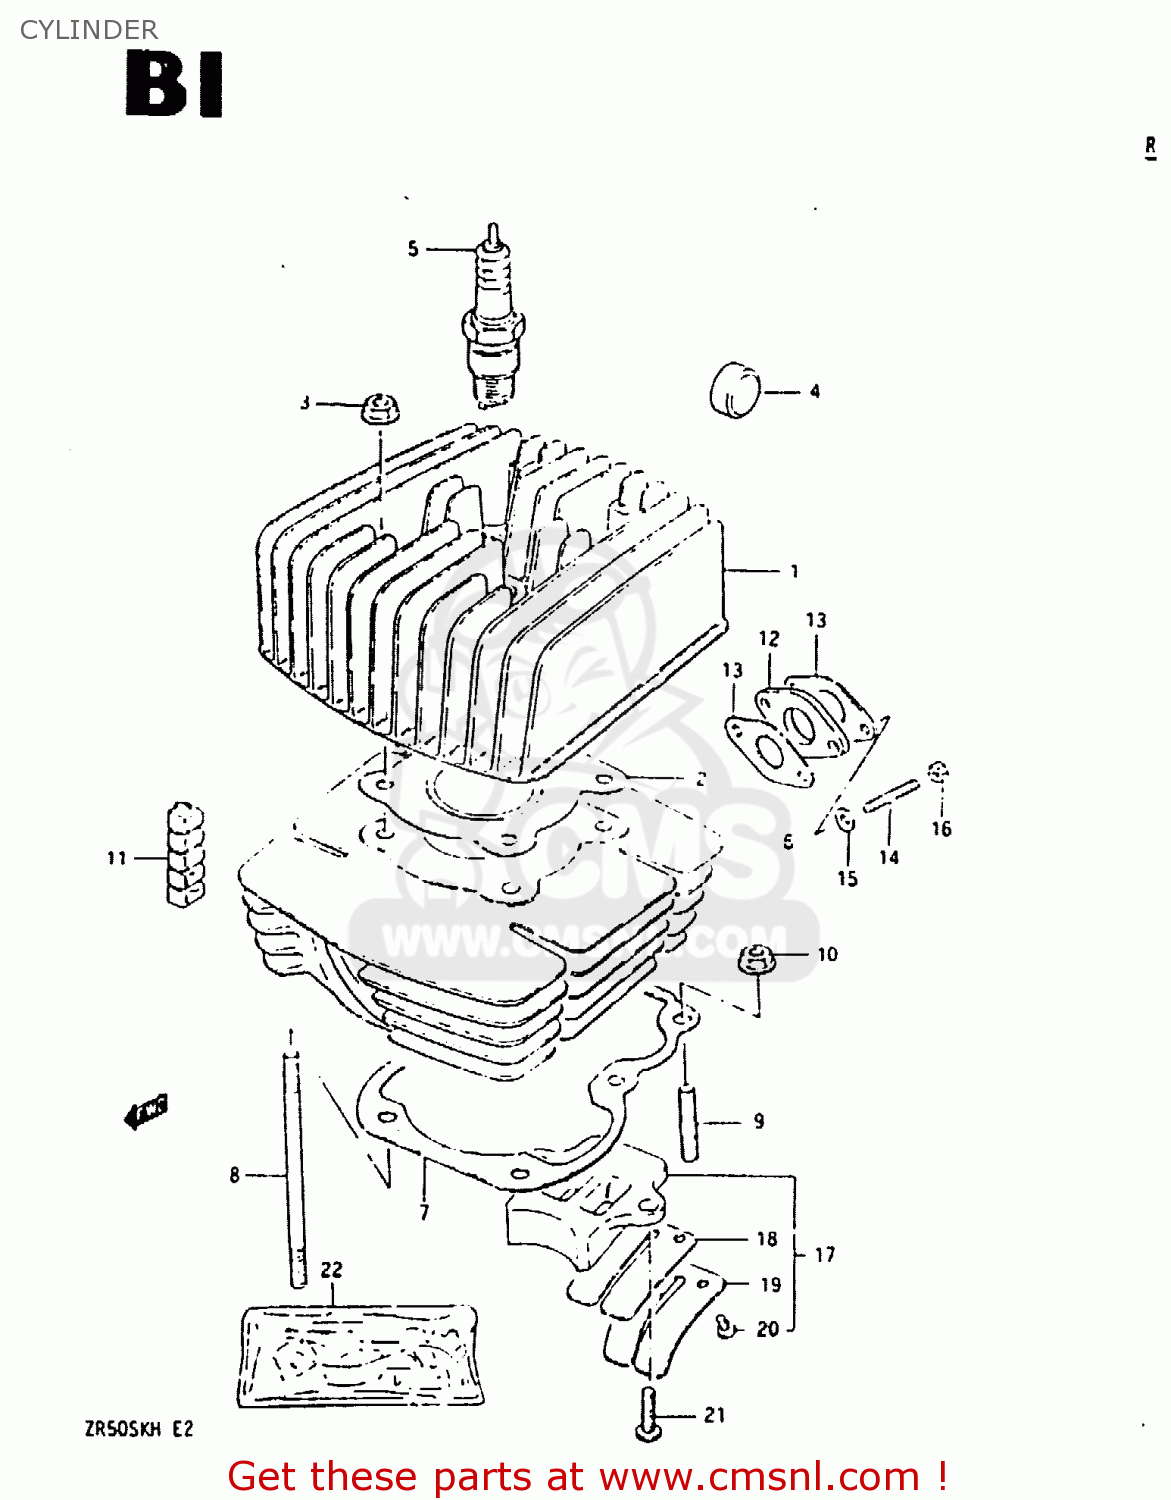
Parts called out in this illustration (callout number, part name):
1	CYLINDER HEAD
2	GASKET,CYLINDER HEAD (NAS)
3	NUT
4	PAD,CYLINDER
5	SPARK PLUG BP8ES
6	CYLINDER
7	GASKET,CYLINDER (MCA)
8	BOLT,STUD
9	STUD 6X16
10	NUT
11	PAD,CYLINDER
12	INSULATOR,CARBURETOR
13	GASKET,CARBURETOR (MCA)
14	STUD BOLT
15	WASHER
16	NUT
17	VALVE ASSY,REED
18	VALVE,REED
19	STOPPER,REED VALVE
20	SCREW,REED VALVE
21	SCREW
22	GASKET SET
